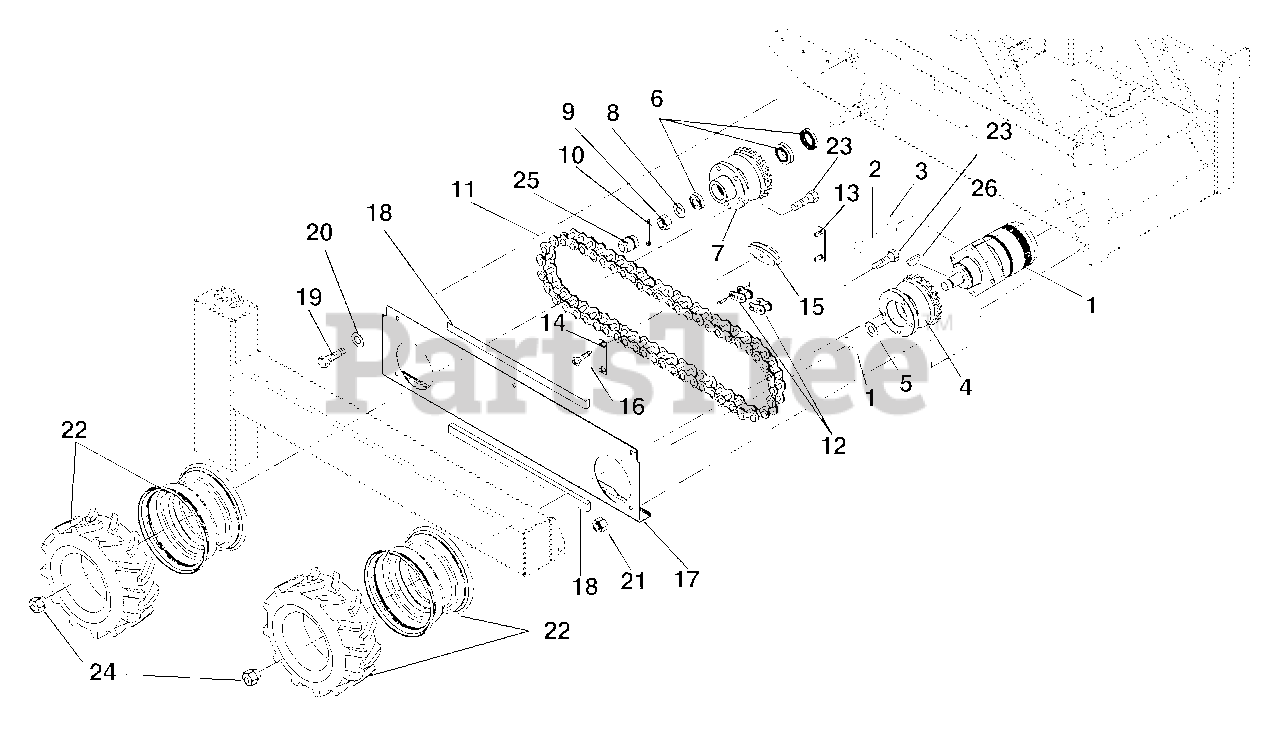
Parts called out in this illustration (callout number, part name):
1	Motor-Wheel
1	Seals, Hydraulic Motor
1	Seals, Hydraulic Motor Hi-Temp
2	Bolt-Hex M16-2 x 40 Class 10.9
3	Washer-Flat-Steel .63 x 1.005 x .062
4	Hub-Front Drive
5	Washer-Flat-Steel 1.062 x 2.0 x .134
6	Bearing-Wheel Set
7	Hub-Rear Idler
8	Washer-Hardened-Thrust .758 x 1.23 x .031
9	Nut-Slotted .75-16
10	Pin-Cotter .12 x 1.25
11	Chain-60 Roller
12	Link, Master Half
13	Bracket-Chain Tensioner
14	Bracket-Retainer Plate
15	Guide-Chain Tensioner
16	Screw-Socket Flat Head M8-1.25
17	Guard-Chain Right Hand
17	Guard-Chain Left Hand
18	Gasket-Foam with Adhesive Back
19	Bolt-Hex M8- 1.25 x 16
20	Washer-Flat-Steel .344 x .688 x .065
21	Nut-Locking-Nylon M10-1.5
22	Wheel-Lug Assembly Right Hand
22	Wheel-Lug Assembly Left Hand
22	Tire-Lug 20 x 8.00-10
22	Tube-20 x 8.00-10
23	Bolt-Wheel Lug .44-20 x 1.38
24	Nut-Lug .437-20
26	Key-Woodruff .31 x 1.00
